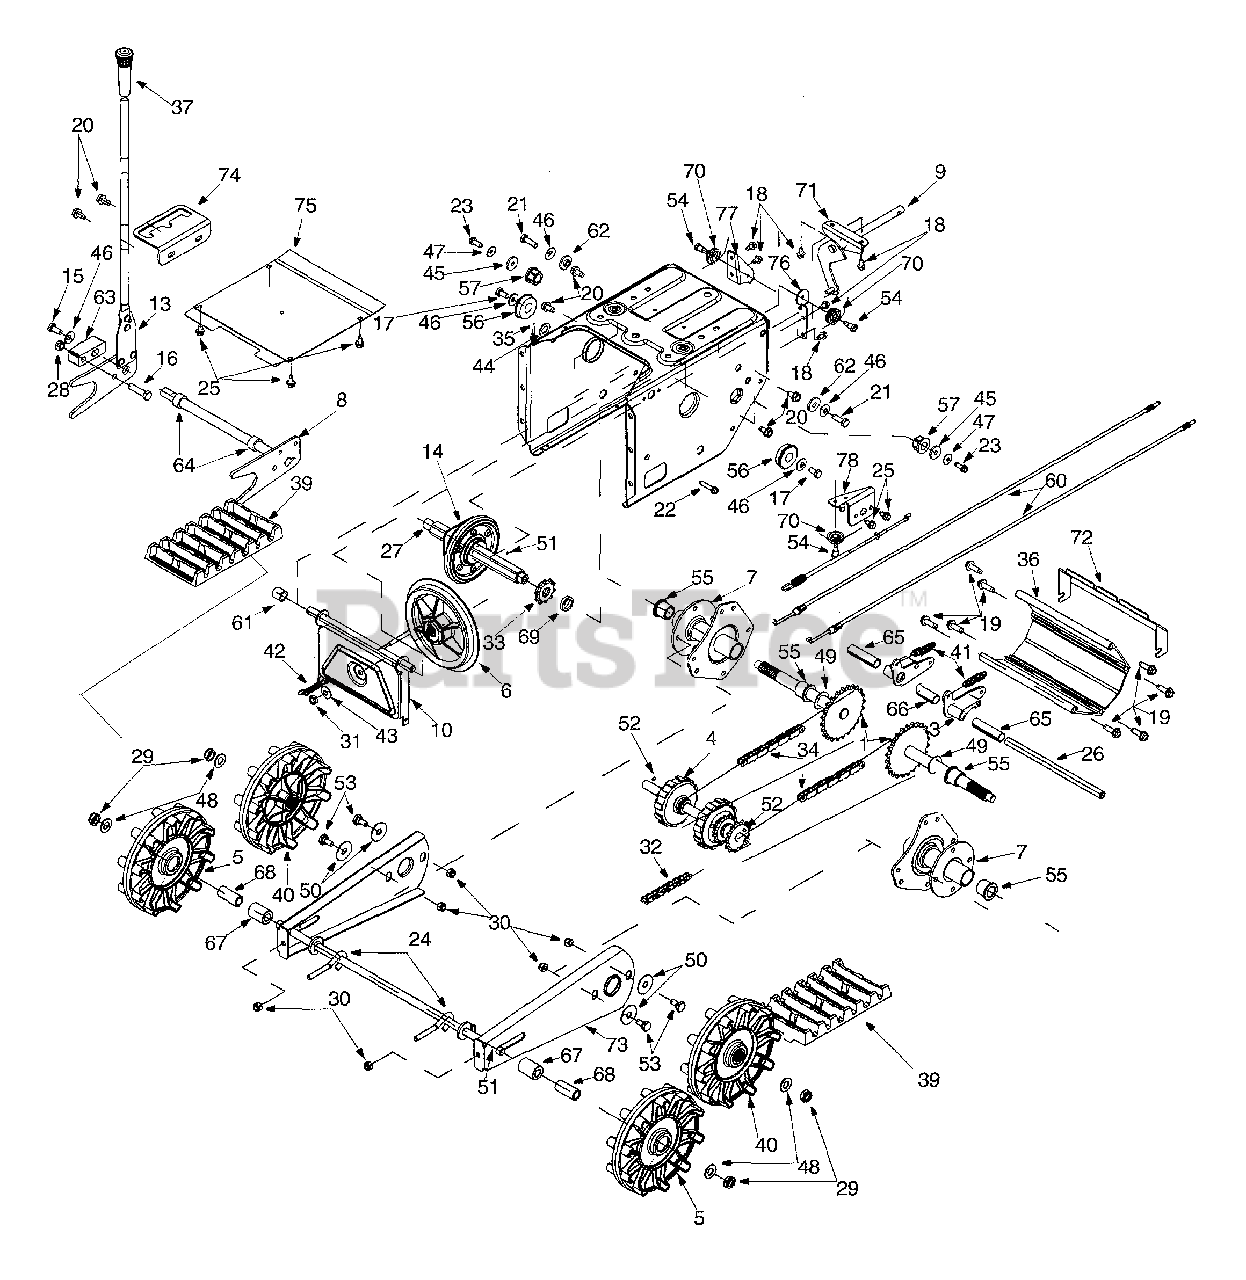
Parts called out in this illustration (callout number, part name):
3	Dogg Assembly: LH
4	Drive Shaft Assembly
5	Idler Wheel Assembly
6	Friction Wheel Disc
14	Wheel Ass'y.: Fric. Whl. Bearing
15	Hex Screw: 5/16-24 x 0.75"
16	Hex Screw: 3/8-24 x 1.5"
17	Hex Screw: 5/16-18 x .625"
18	TT Screw: 1/4-20 x 0.5"
19	TT Screw: 5/16-18 x 1.0"
20	TT Screw: 5/16-18 x 0.625"
21	Hex Bolt: 5/16-18 x 1.0"
22	TT Screw: 1/4-20 x 1.25"
23	TT Screw: 1/4-20 x 0.75"
24	Eye Bolt
25	TT Screw: 1/4-20 x 0.625"
26	Actuator Shaft
27	Hex Shaft: Drive
28	Hex Lock Nut
29	Jam Lock Nut
30	Hex Lock Nut
31	Jam Nut
32	Chain
33	Sprocket
34	Chain
35	Cotter Pin
36	Track Housing
39	Track
40	Track Wheel
41	Extension Spring
42	Extension Spring
43	Spring Washer
44	Flat Washer
45	Flat Washer
46	Beleville Washer
47	Bell Washer
48	Flat Washer
49	Flat Washer
50	Flat Washer
51	Lubricant
52	Grease
53	Shoulder Screw
54	Carriage Screw
55	Flange Bearing
56	Ball Bearing
57	Hex Flange Bearing
60	Steering Cable
61	Spacer
62	Shoulder Spacer
63	Lift Shaft Drive
64	Spacer
65	Split Spacer
66	Split Spacer
67	Spacer
68	Spacer
69	Spacer
70	Cable Roller
